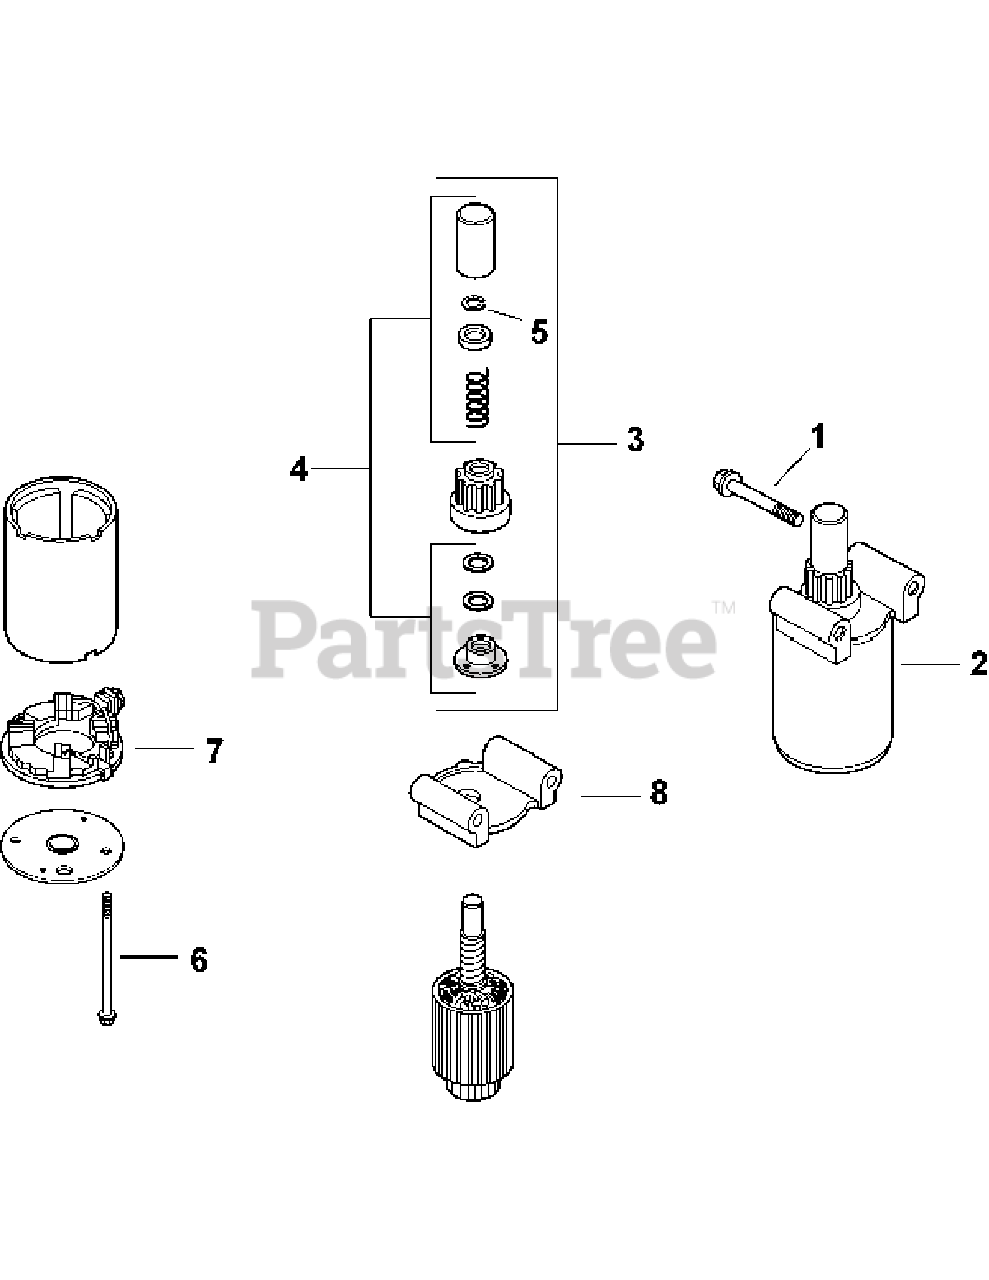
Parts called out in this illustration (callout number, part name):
1	Screw, FLG M8 x 1.25 x 80
2	Starter Assembly
4	Kit, Drive Parts
5	Ring, Retaining
7	Commutator, End Cap
8	Cap, Drive End
